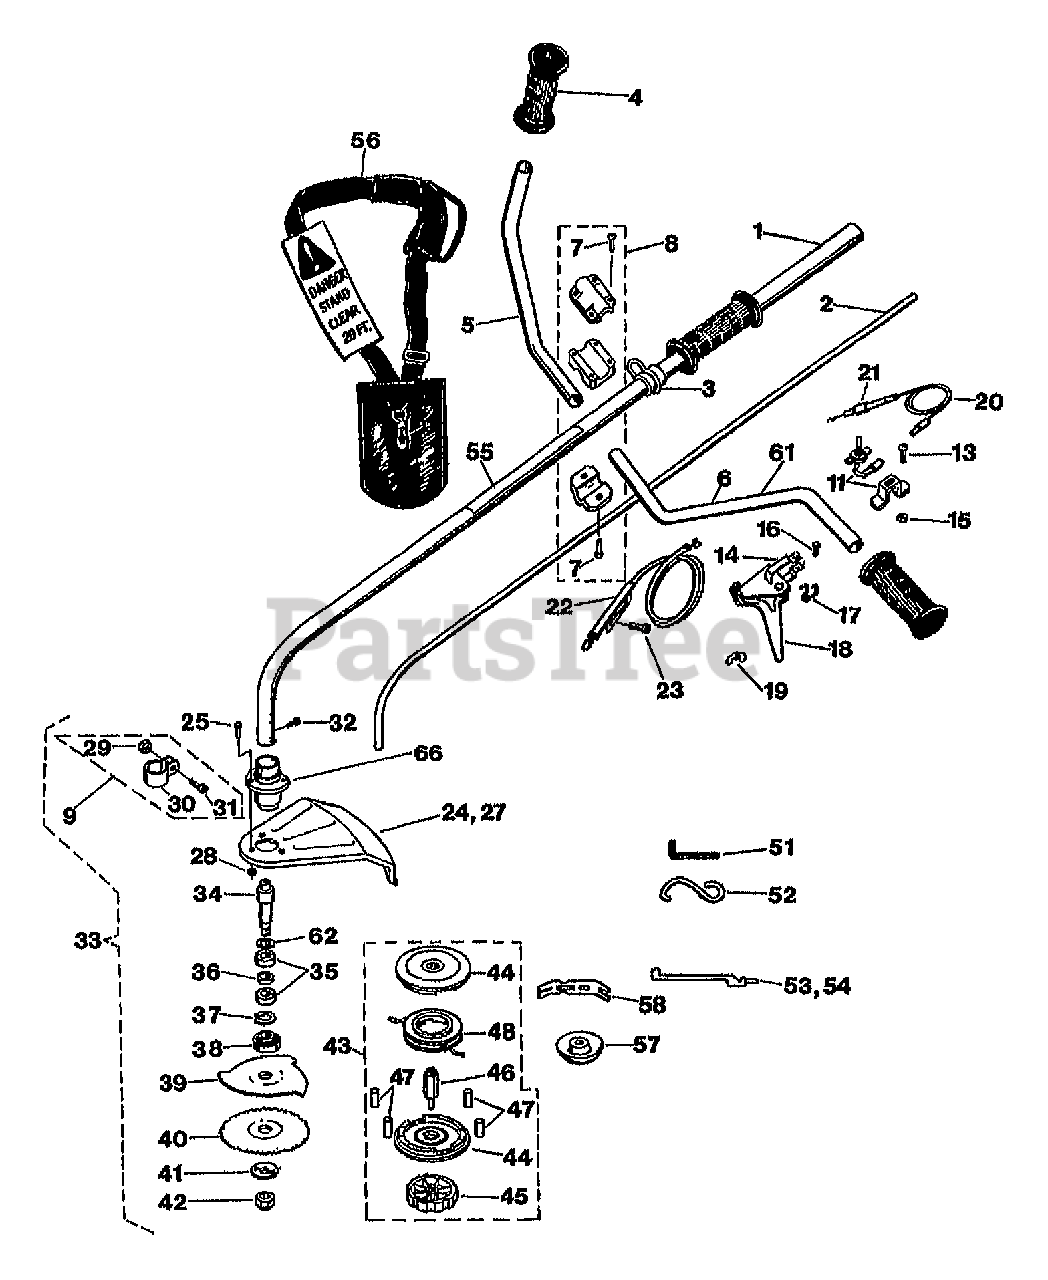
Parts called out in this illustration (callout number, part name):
1	HOUSING-DRIVESHAFT
2	SHAFT-DRIVE 5/16X57"
3	RING-CARRYING
4	GRIP-HANDLEBAR
5	H/BAR-RH W/GRIPS
6	HANDLEBAR-LH W/GRIP
7	SCR-HXSKT 1/4-20X.75 (ONLY AVAILABLE IN ITEM NO. 8)
8	KIT-H/BAR CLAMP (INCL. 7)
9	KIT (INCL. 29-31)
11	SWITCH-ON/OFF (INCL. BRACKET)
13	SCR-PHP M10-32X.75 ZP
14	KIT-CLAMP TRG. H205596
15	NUT-HH M10-32X.125
16	SCREW, HEX HD 10-32X1 THROTTLE CONTROL
17	SPRING, THROTTLE CONTROL
18	ASSM-TRIGG H205532
19	NUT, WING 10-32 THROTTLE CONTROL
21	WIRE CONNECTOR & COVER
22	CABLE-THROTTLE
23	SCR W/SERRATED WASHER
24	SHIELD-GRASS (INCL. 25,27,28)
25	SCR.& NUT
27	SHIELD-GRASS
28	KIT-HDW DUSTSHIELD
29	NUT-HF/LK 1/4-20 ZP
30	CLAMP, LOWER HEAD (ONLY AVAILABLE IN #9)
31	SCR-HXSKT 1/4-20X.75
32	SCR #10-32X5/16
33	ASSM-LOWER HEAD (INCL. 9,34-38,41,42 62, AND 66)
34	LOWER ARBOR-SQUARE
36	ASSM-LOWER HEAD SPACER
37	RING-RETAINING
38	WASHER-CUP
39	BLADE-8" TRIKUT HOFFCO
40	BLADE-8" BRUSHCUTTER
41	WASHER-ARBOR 3/8
42	NUT W/NYLON INSERT 3/8-24
43	MONOFILAMENT HEAD-2 LINE (INCL. 44-48)
44	HOUSING-MONOFILAMENT HEAD
45	KNOB-RH MONOFILAMENT HEAD
46	ARBOR-MONOFILAMENT HEAD
47	LINE SAVER-MONOFIL HEAD
48	SPOOL-15'H2 #H211524
51	WRENCH-ALLEN 3/16
52	LOWER HEAD TOOL
53	STRAP-TIE 7/8
55	DECAL-H/B LUBE INST
56	HARNESS W/HIP PAD RH
56	HARNESS-LEFT HAND
57	KIT-GLIDE BALL
58	TEMPLATE-GAUGE(FILING)
61	DECAL, MADE IN AMERICA
66	AVAILABLE IN ITEM NO. 33
